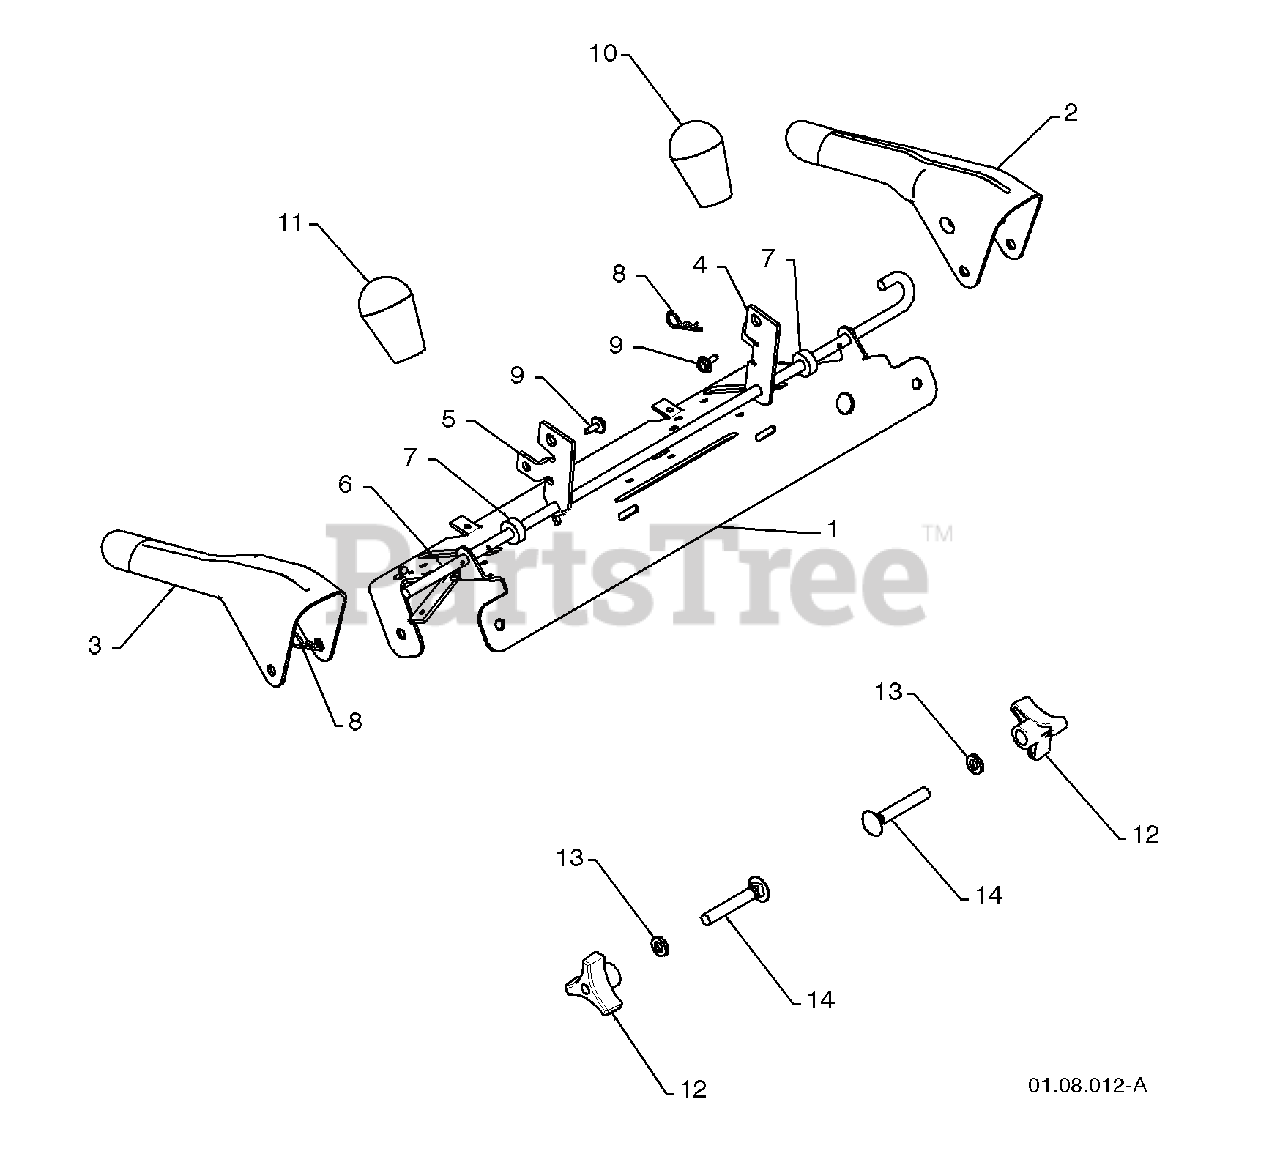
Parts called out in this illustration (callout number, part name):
1	CONTROL PANEL
2	CONTROL LEVER LH
3	CONTROL LEVER RH
4	TRACTION ROD ARM
5	IMPELLER ROD ARM
6	INTERLOCK ROD
9	SCREW 1/4-20 X .50
10	KNOB BLACK
12	HANDLE KNOB
13	WASHER 3/8
14	CARRIAGE BOLT 3/8-16 X 2.25
